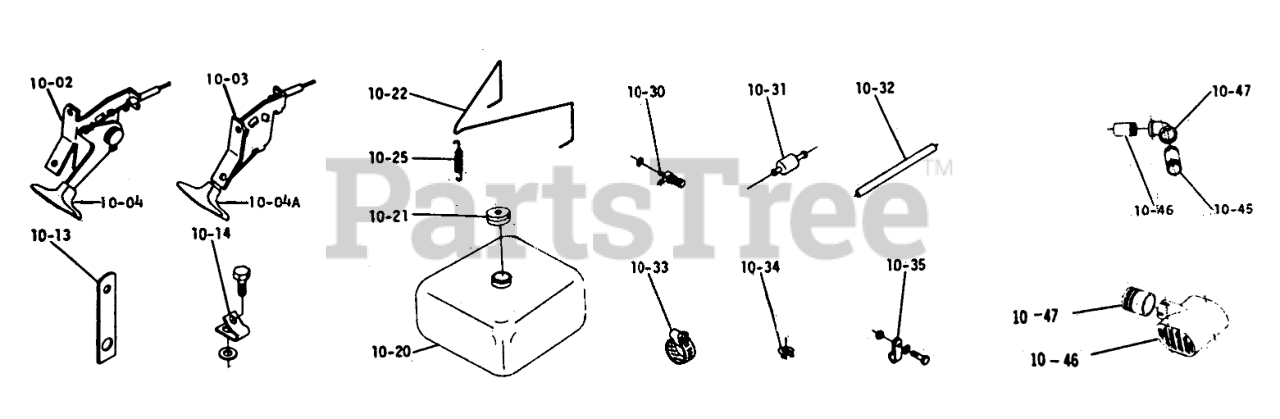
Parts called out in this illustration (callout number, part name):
10-02	Choke Control
10-03	Throttle Control Assy.
10-04	KNOB-CHOKE
10-04A	KNOB-THROTTLE
10-13	Strap
10-14	THROTTLE CONTROL CLP
10-20	Fuel Tank
10-21	Cap
10-22	Hold Down Wire
10-25	CLUTCH SPRING
10-30	S/A FUEL VALVE
10-31	Filter
10-32	Fuel Hose
10-33	CLAMP
10-34	Clamp
10-35	CLAMP-HOSE
10-45	Nipple 1" Pipe x 2"
10-46	MUFFLER
10-47	Nipple
